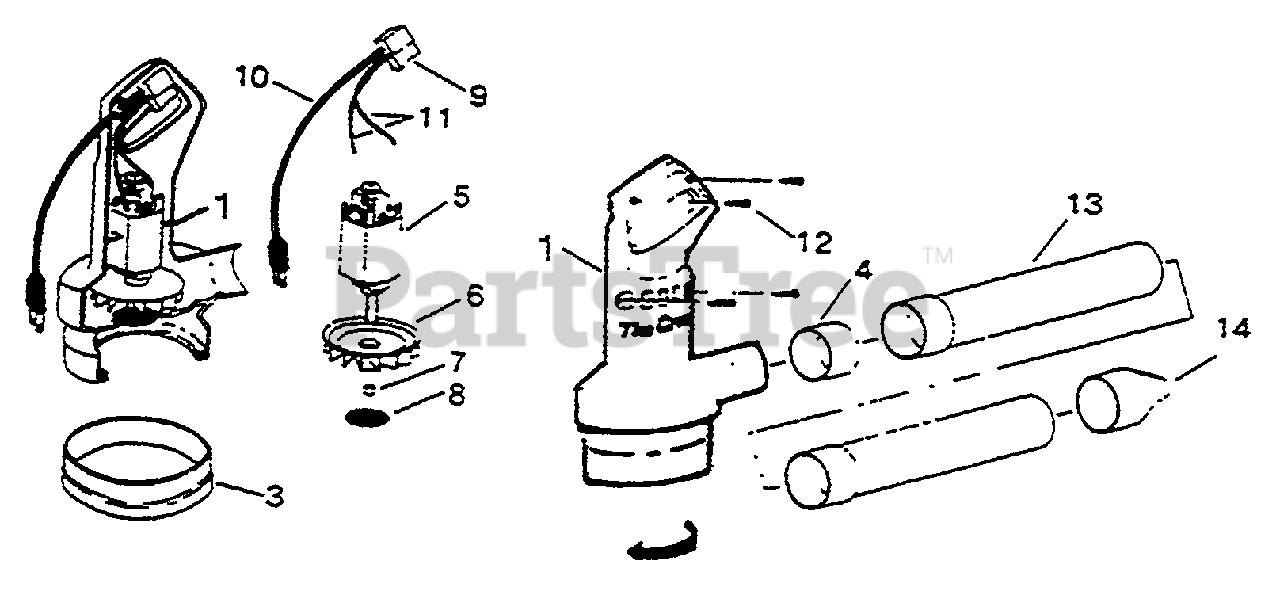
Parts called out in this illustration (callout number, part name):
1	HOUSING SET
3	RING INLET
4	RING DISCHARGE
5	MOTOR
10	SUPPLY CORD
12	SCREW
15	SCREEN DISCHARGE
16	NUT, MOTOR
17	WASHER, FLAT
